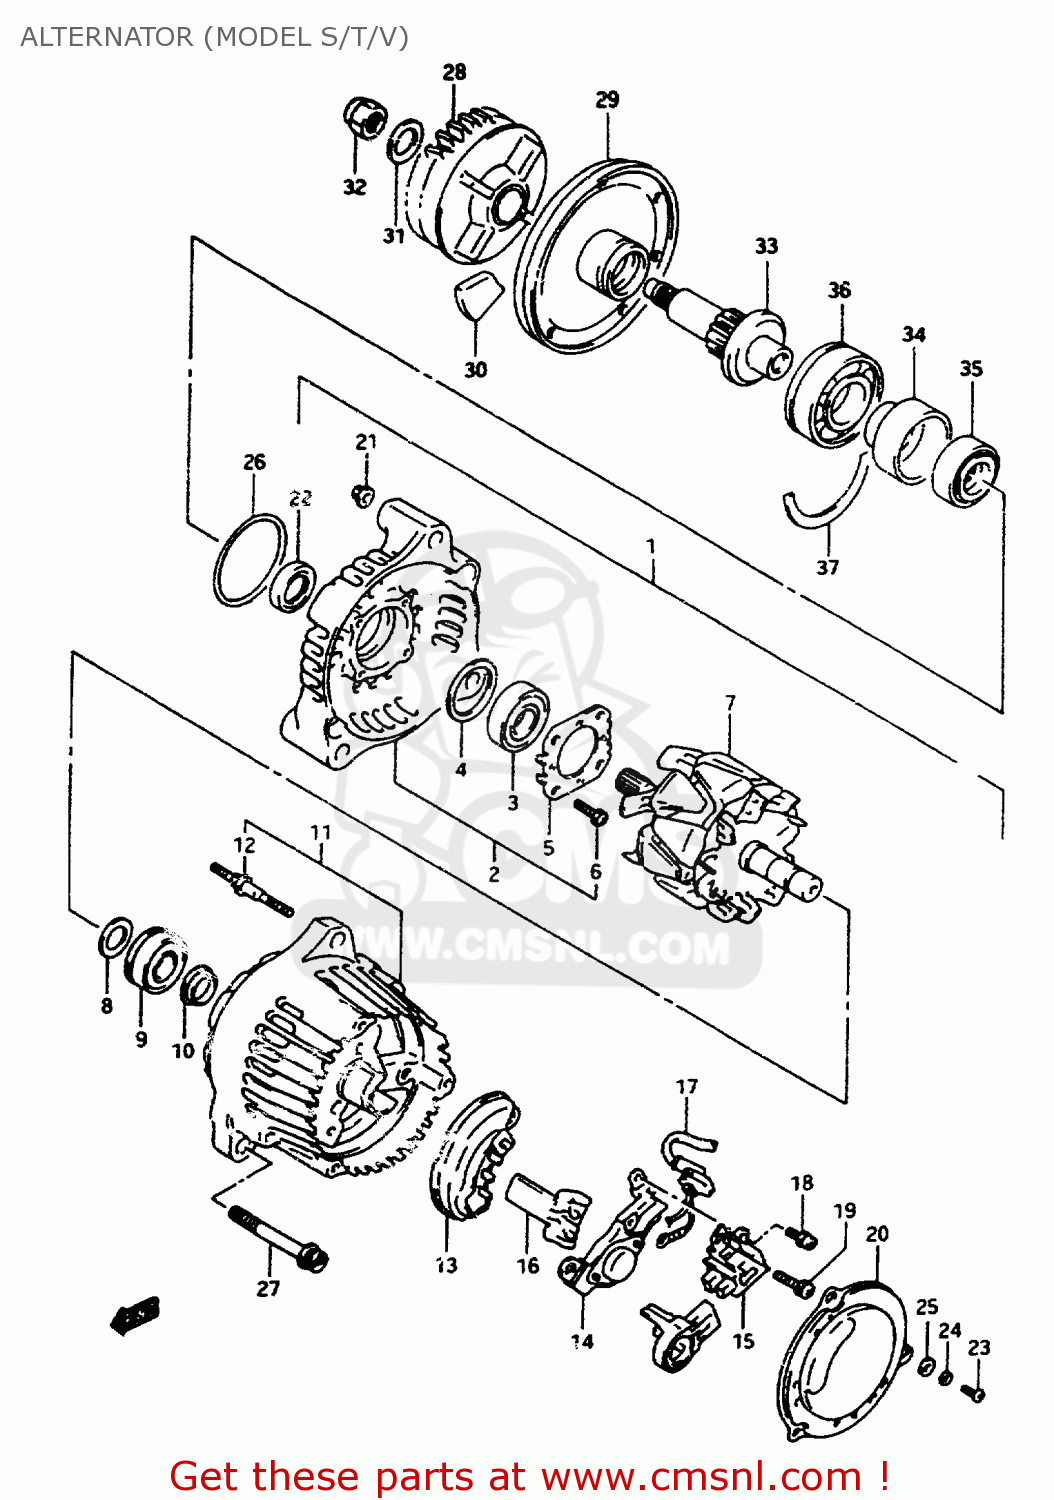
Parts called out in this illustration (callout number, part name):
1	ALTERNATOR ASSY
2	FRAME,DRIVE END
3	BEARING
4	COVER,BEARING
5	RETAINER,BEARING
6	SCREW,BEARING RETAINER
7	ROTOR ASSEMBLY
8	COVER,BEARING
9	BEARING
10	COVER(2)
11	FRAME,END
12	STUD BOLT
13	HOLDER,RECTIFIER
14	REGULATOR
15	HOLDER,BRUSH
16	COVER,RECTIFIER
17	WIRE,LEAD
18	SCREW 4X6
19	SCREW
20	COVER
21	NUT
22	SERVICE KIT(A)
23	SCREW
24	LOCK,WASHER
25	WASHER
26	O RING
27	BOLT
28	GEAR,GENERATOR DRIVEN
29	HOUSING,GENERATOR DAMPER
30	DAMPER,GENERATOR
31	WASHER
32	NUT
33	SHAFT,GENERATOR DRIVE
34	HUB,GENERATOR DRIVE
35	COUPLING COMP,GENERATOR
36	CIRCLIP
37	C RING
